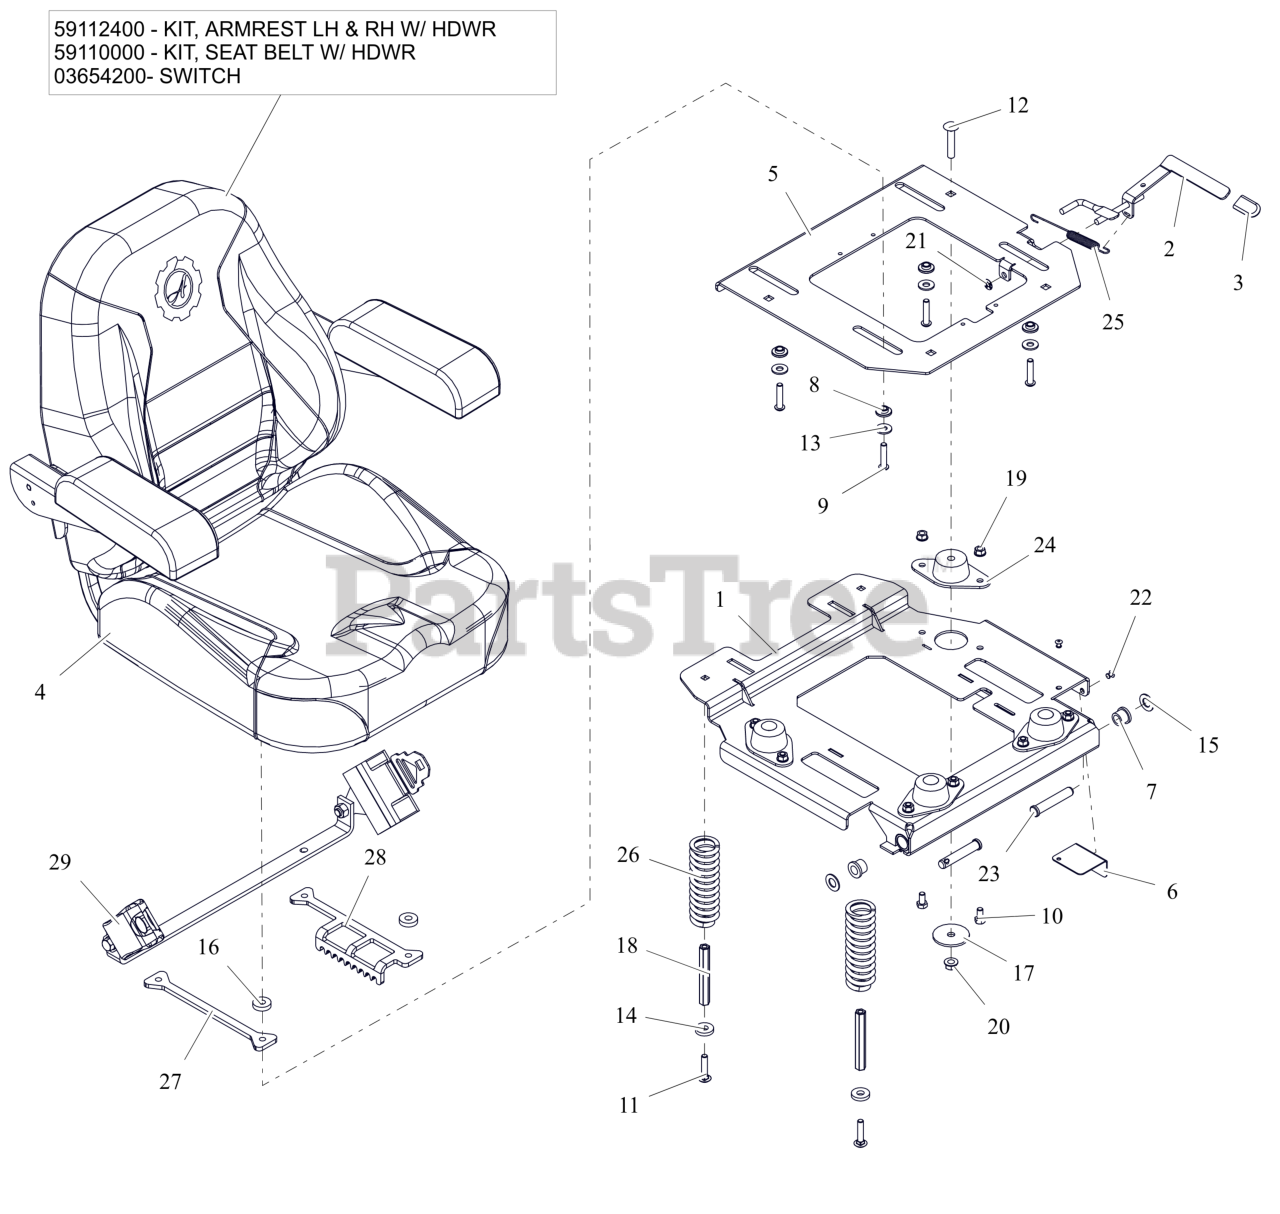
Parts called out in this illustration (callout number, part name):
1	WLDMT, ISO MTG PLATE (BLACK)
2	WLDMT, SEAT SLIDE LEVER
3	GRIP, SEAT LEVER, GREY
4	SEAT, APEX
4	KIT-LH & RH ARM REST-05124700
4	KIT-SEAT BELT REPLACE-05007300
4	SWITCH- SEAT
5	PLATE, SEAT MOUNTING (ISO KIT) (ORANGE)
6	GUARD, SEAT FAN (SH)(BLACK)
7	BSHG, FLG .516X.750X.625X.937
8	BSHG-FLG .325X.499X.3X.875
9	BLT,SHCS-BTN .31-18X1.50 ZCC
10	BLT, HEX .31-18X.625 G5 ZCC
11	BLT,RHSN .31-18X1.50 G5 ZCC
12	BLT,RHSSN.375-16X2.00 G5 ZCC
13	WSHR,FLT .375X.875X.083 ZCC
14	WSHR, FLT .406X1.00X.188 ZCC
15	WSHR, FLT .531X1.00X.063 ZCC
16	WSHR, FLT .390X1.00X.250 ZCC
17	WSHR-FL-STL 0.406X2X0.125 ZCC
18	NUT, COUPLING 5/16X18 X 3.75
19	NUT,LK-CTR-FLG .31-18 GF ZCC
20	NUT-LK-CTR-FLG .375-16 GF ZCC
21	NUT-PUSH .312
22	RIVET, .1875 AL/AL .126-.250
23	PIN-CLIC .50X2.70X2.31 -ZCC
24	MOUNT, FAIL-SAFE COMPRESSION
25	SG-TENS .06X.482X5.35
26	SPRING, COMPRESSION SEAT 224LB
27	PLATE, ADJ SEAT SLIDE (BLACK)
28	PLATE, SEAT ADJ (BLACK)
29	KIT-SEAT BELT REPLACE-05007300
